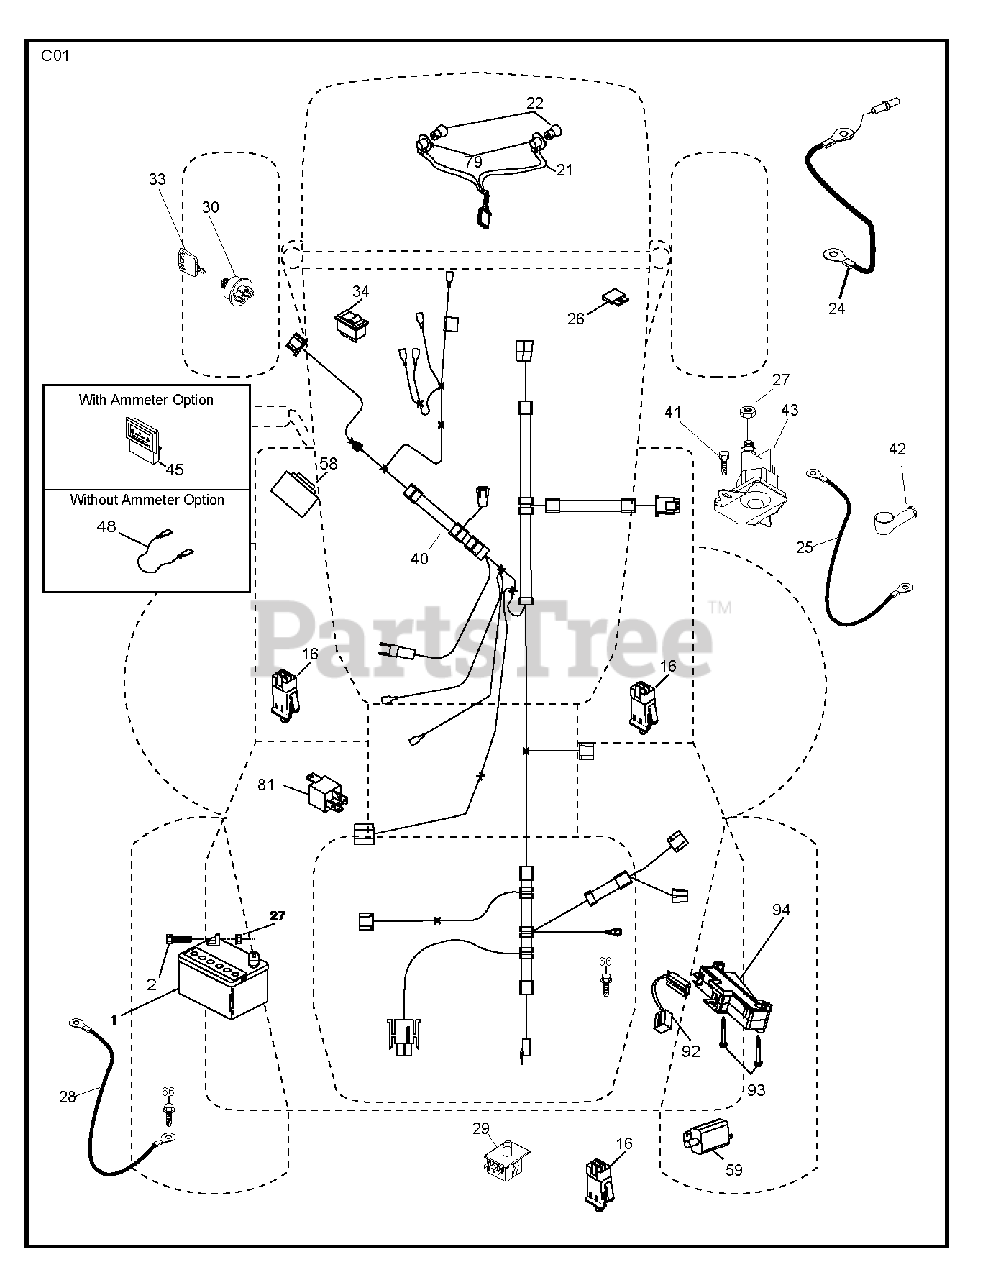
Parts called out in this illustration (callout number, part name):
1	REPL BY 532 12 38-99
16	SWITCH INTERLOOK PUSH-IN
21	HARNESS ASSY LIGHT
24	CABLE BATTERY 6 GA. 11" RED
25	CABLE BATTERY
27	NUT
29	SWITCH.SEAT.DP W/RAMPS
30	SWITCH.IGN.DELTA.W.LGH.ROS
33	KEY.CHAIN.BLISTER.PACK.GEN.INT
41	Hex Capscrew, 1/4-20
42	TERMINAL COVER
43	SOLENOID.W/BRASS.PLUNG
58	BUZZER
79	BULB HOLDER ASM.
92	HARNESS.PIGTAIL.CONSLE
93	SCREW.PLASTITE
94	MODULE.REVERSE.ROS
